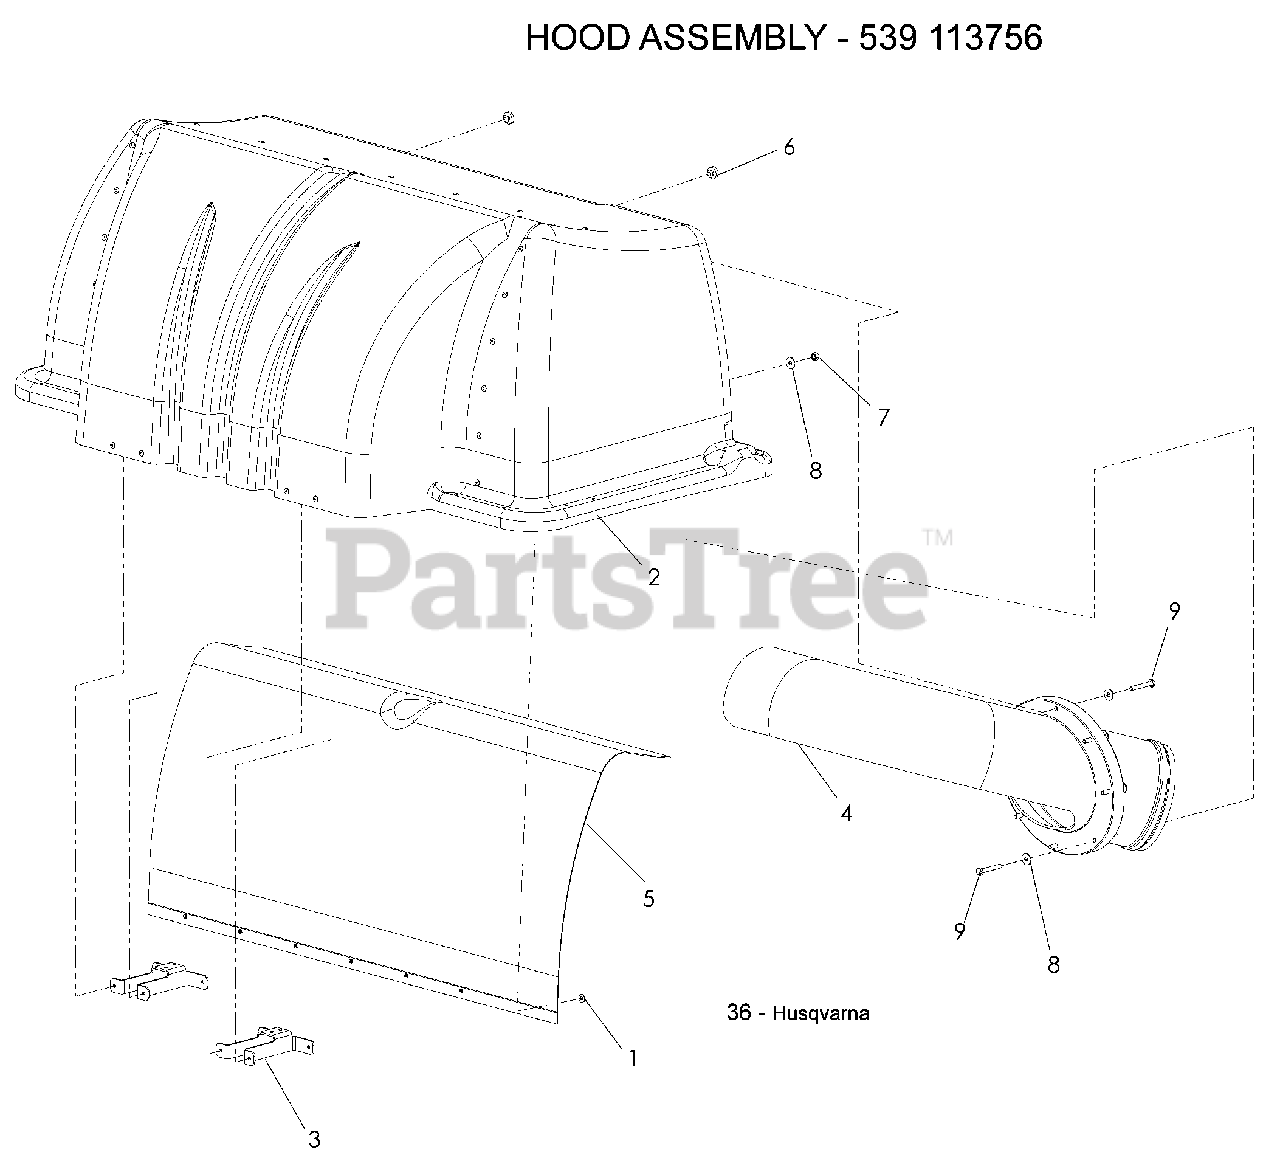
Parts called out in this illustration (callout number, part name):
1	WASHER #10
3	SUPPORT, DRAW LATCH
4	INLET TUBE
5	MESH, POLY DIAMOND
7	NUT ¼-20 HEX NYLOC
9	HCS ¼-20 x 1¾
